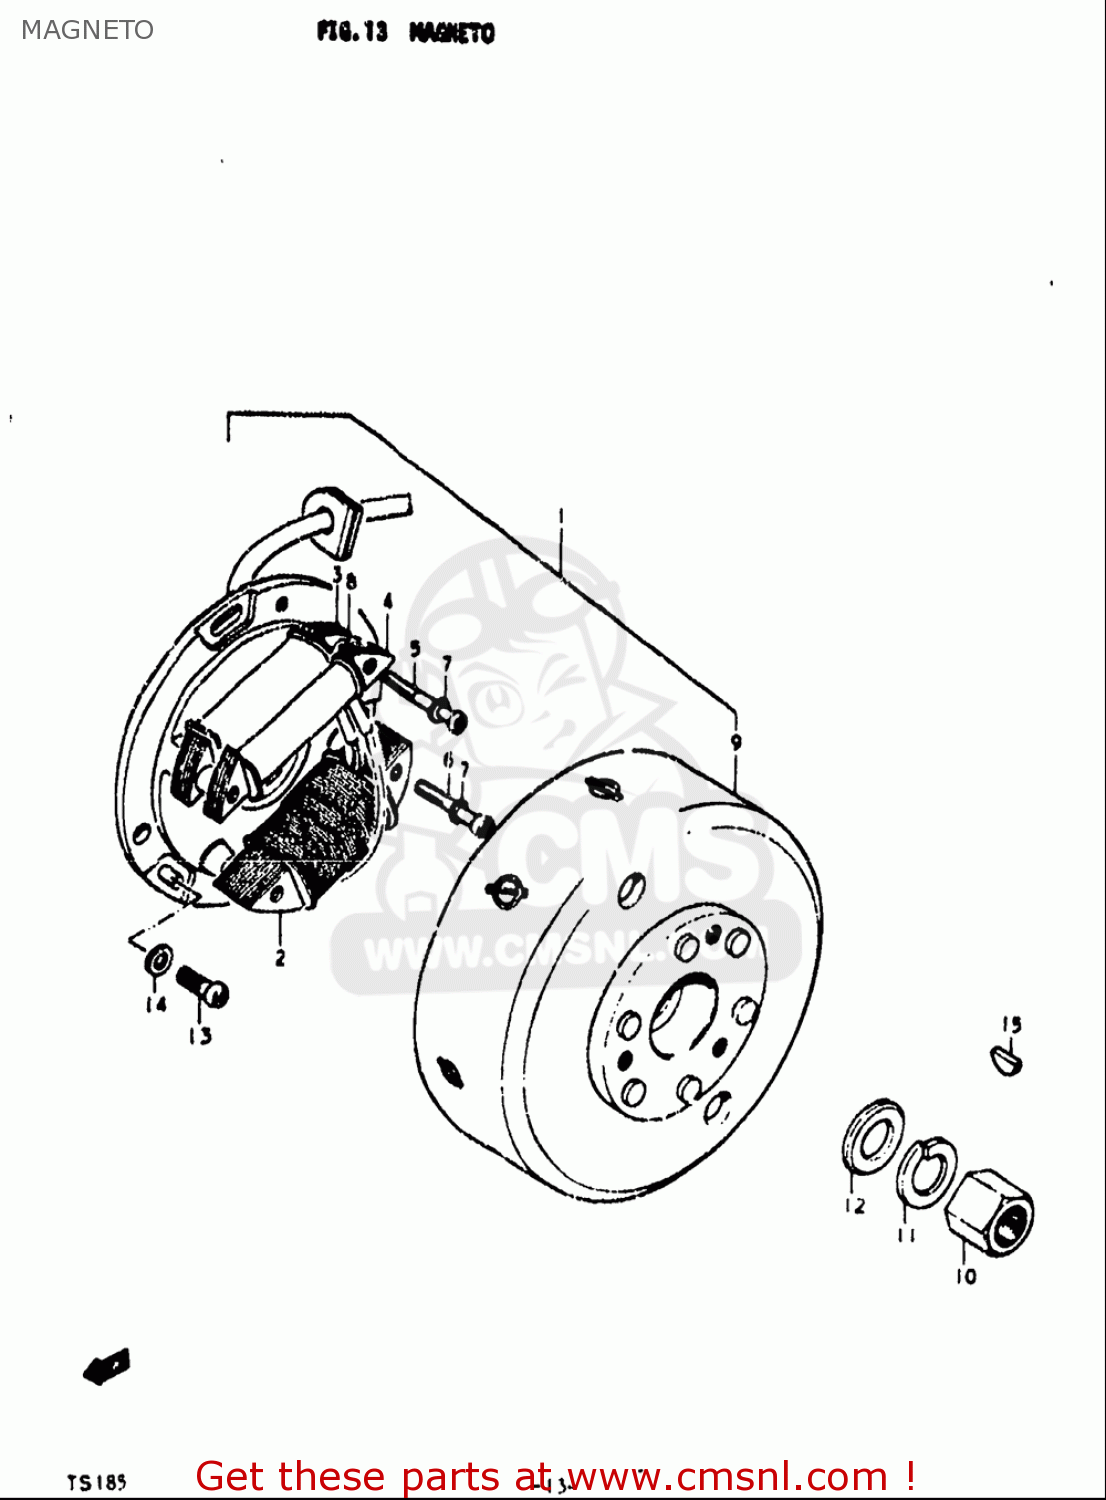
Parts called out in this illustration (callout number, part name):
5	SCREW
6	SCREW(4X30)
7	WASHER,LOCK
10	NUT
11	WASHER,LOCK
12	WASHER(14X27X3)
13	SCREW
14	WASHER
15	KEY
